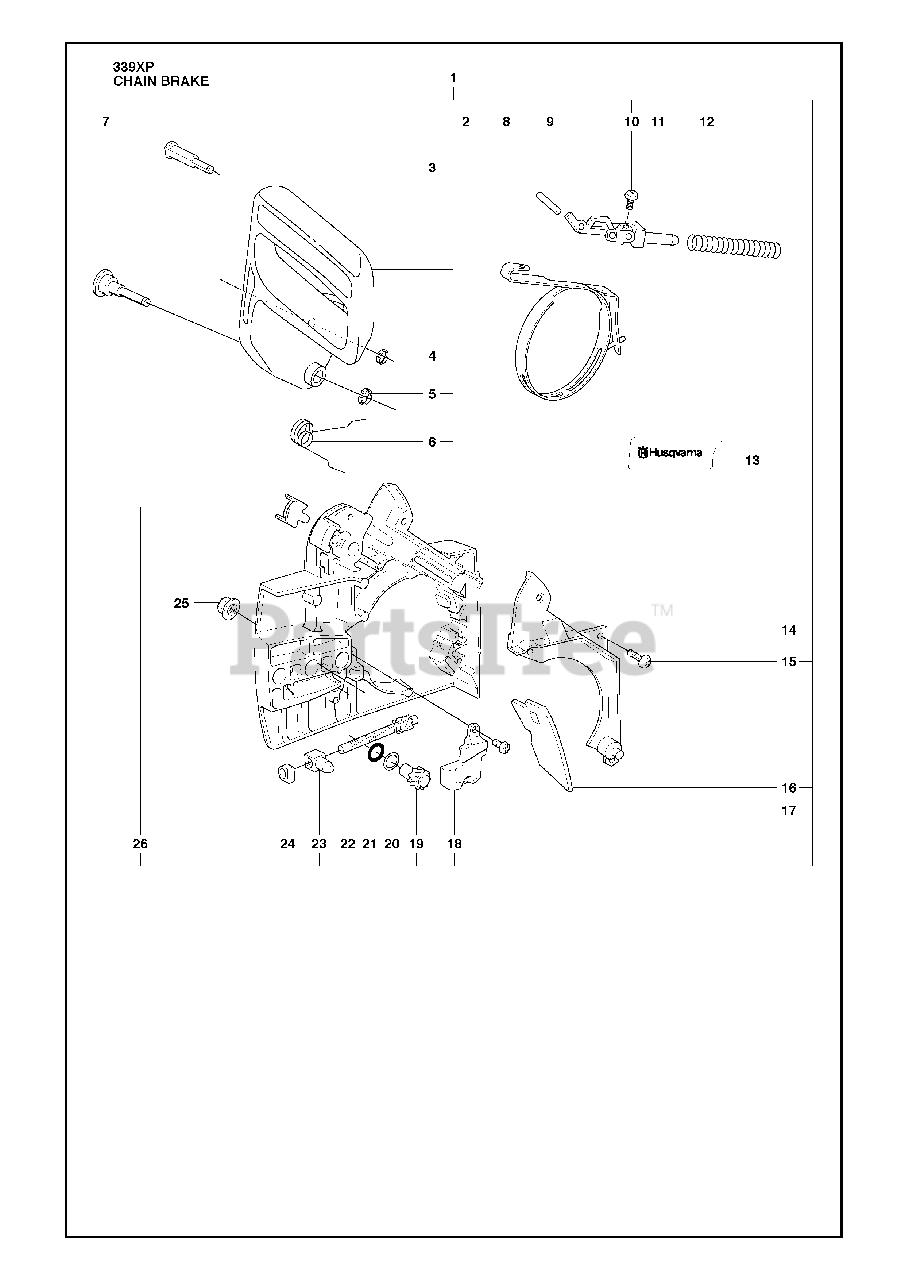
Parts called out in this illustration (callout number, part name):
1	CHAIN BRAKE ASSY
2	HAND GUARD
6	POSITION SPRING
7	SHAFT PIVOT
8	BRAKE BAND ASSY
11	KNEE-JOINT
12	SPRING
19	WORM WHEEL
23	PAWL
25	NUT M8 FLANGE
